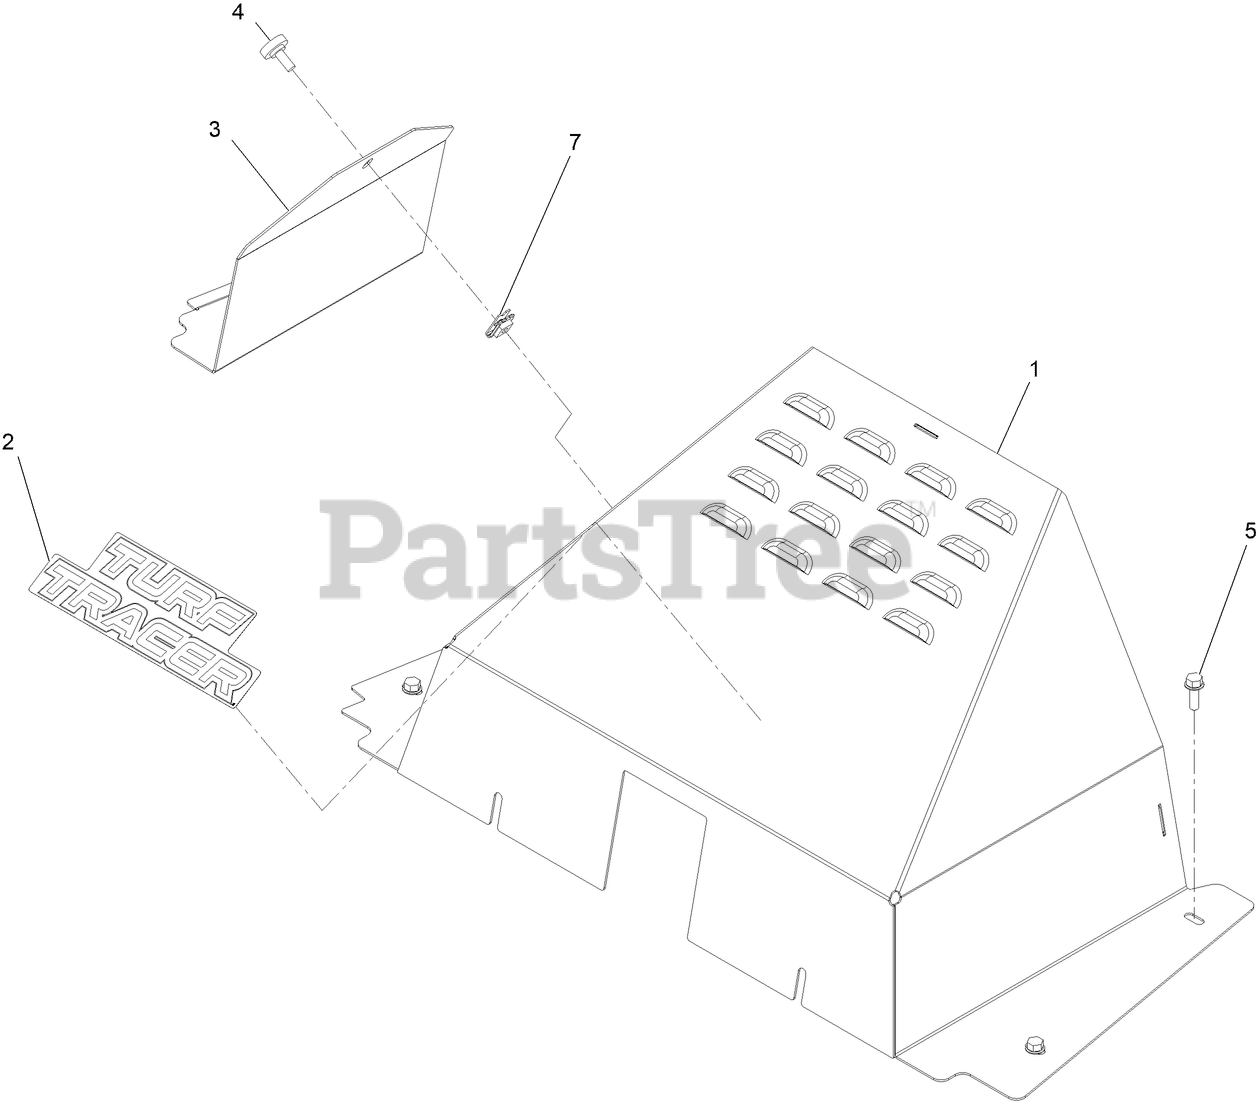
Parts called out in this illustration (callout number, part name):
1	HOOD-FRONT
2	Decal-Turf Tracer
3	PANEL-ACCESS, BATTERY
4	SCREW-THUMB
5	SCREW-HHF
7	Nut-Retainer
